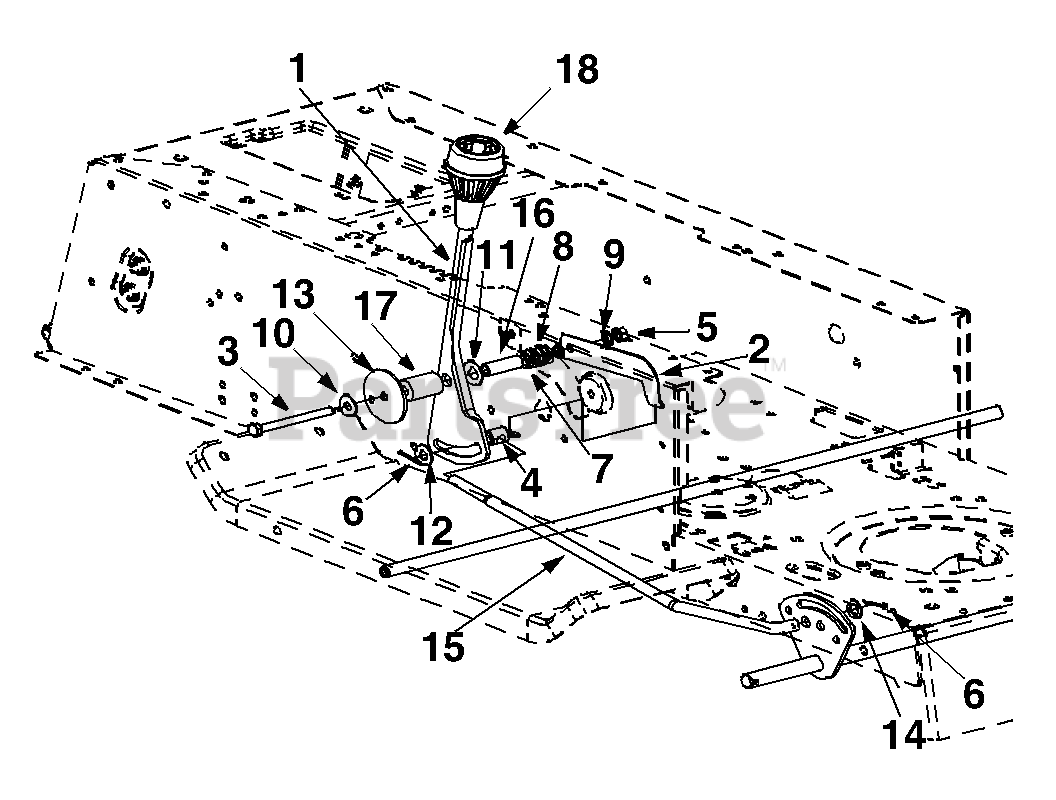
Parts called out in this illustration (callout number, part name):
1	Speed Selector Lever
2	Shift Lever Support
3	Hex Bolt 5/16-18 x 3.25" Lg.
4	Ferrule 3/8-24 Thd.
5	Hex Nut 5/16-18 Thd.*
6	Cotter Pin 3/32" Dia. x 1"
7	Speed Nut 5/16-18 Thd.*
8	Compression Spring
9	L-Wash. 5/16" I.D.*
10	Fl-Wash. .345" I.D. x .88"
11	Bell-Wash. .505" I.D. x 1"
12	Fl-Wash. .385" I.D. x .87"
13	Fl-Wash. .34" I.D. x 2.25"
14	Fl-Wash. .469" I.D. x .75"
15	Speed Control Rod
16	Spacer 1.56" Lg.
17	Spacer 1.46" Lg.
18	Shift Knob
